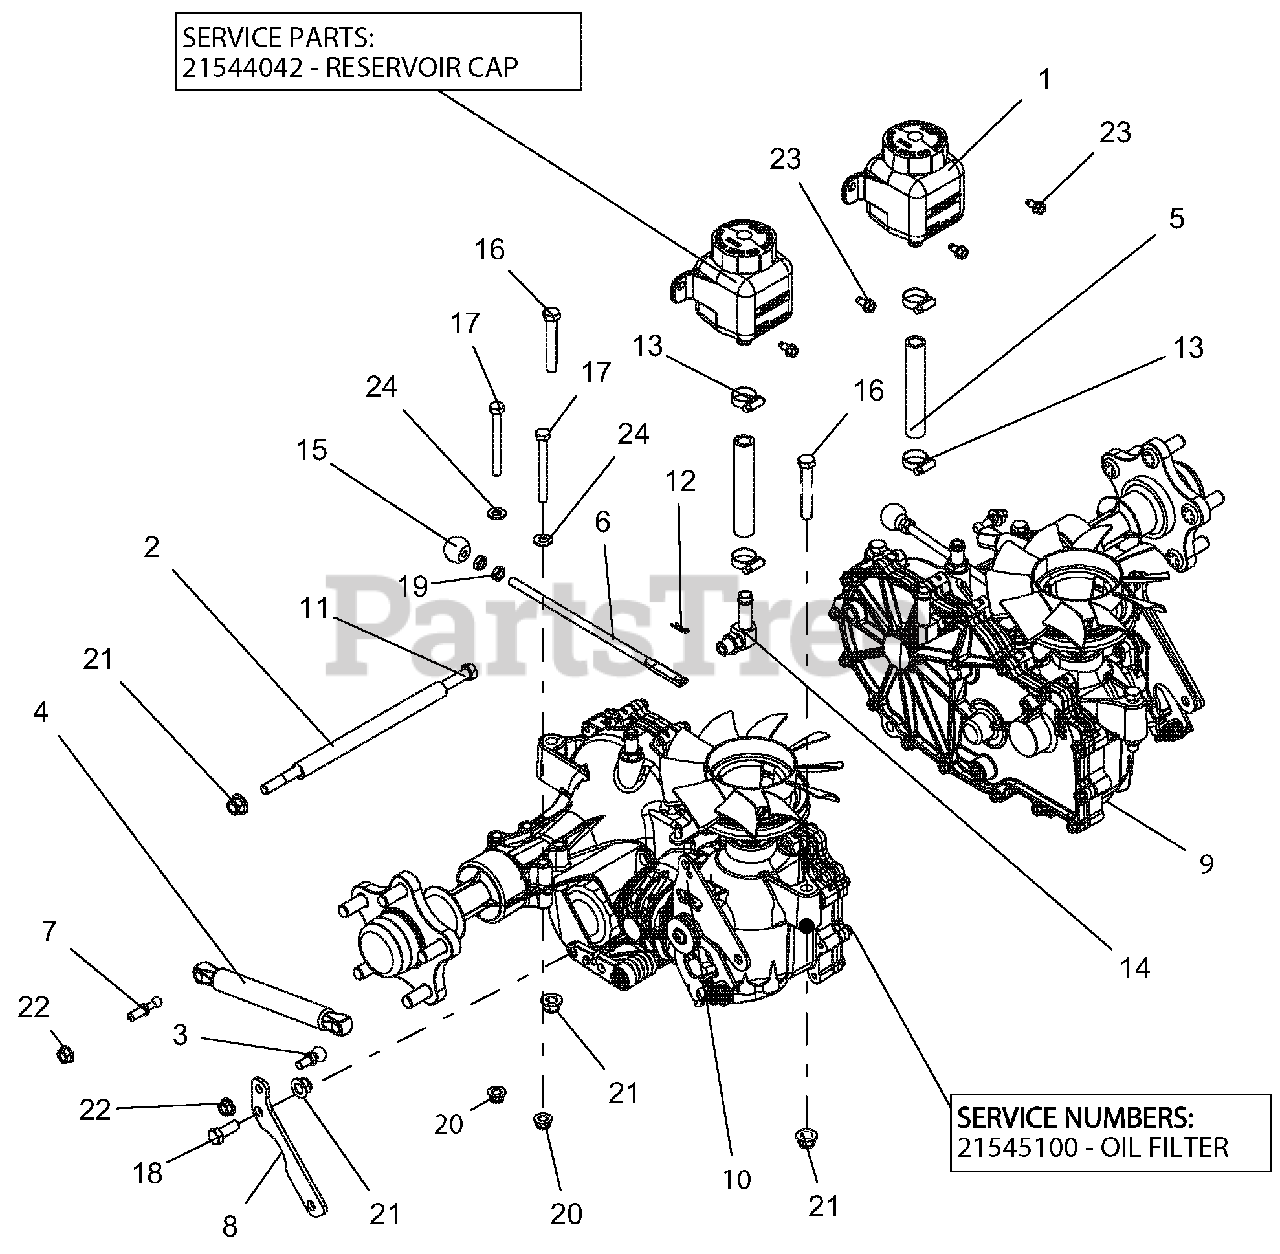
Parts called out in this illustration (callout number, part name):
1	TANK, EXPANSION ZT2800
1	RESERVOIR CAP
2	SPACER, .406 ID X .630 OD X 7.724
3	STUD-BALL
4	DAMPER,
5	HOSE, PT100 HYDRO OVERFLOW
6	LEVER, PT100 DUMP VALVE
7	STUD, BALL THREADED
8	TRANSMISSION DAMPER MTG PLATE - BLK
9	TRANSAXLE, ZT3200 - LH
10	TRANSAXLE, ZT3200 - RH
10	OIL FILTER
11	BLT, HEX .38-16X11.00 GR5 YWZC
12	PIN-HAIR INT .06X.18X.77
13	CLAMP, .88 DIA HOSE
14	FITTING, HYD (90 DEG)
15	KNOB, BALL -BLACK .312-18
16	BLT-HEX .38-16X2.50 GR5 YWZC
17	BLT-HEX .31-18X3.00 GR5 YWZC
18	BLT-HEX .38-16X1.00 GR5 YWZC
19	NUT, JAM .312-18 YWZC
20	NUT-LK-NYL-FLG .31-18 YWZC
21	NUT-LK-NYL-FLG .38-16 YWZC
22	NUT, LK-TOP-FLG .312-18 YWZC
23	SCR-TAP .25-20X.50 HWH TR YWZ
24	WSHR-FL-STL.344X.688X.065YWZC
